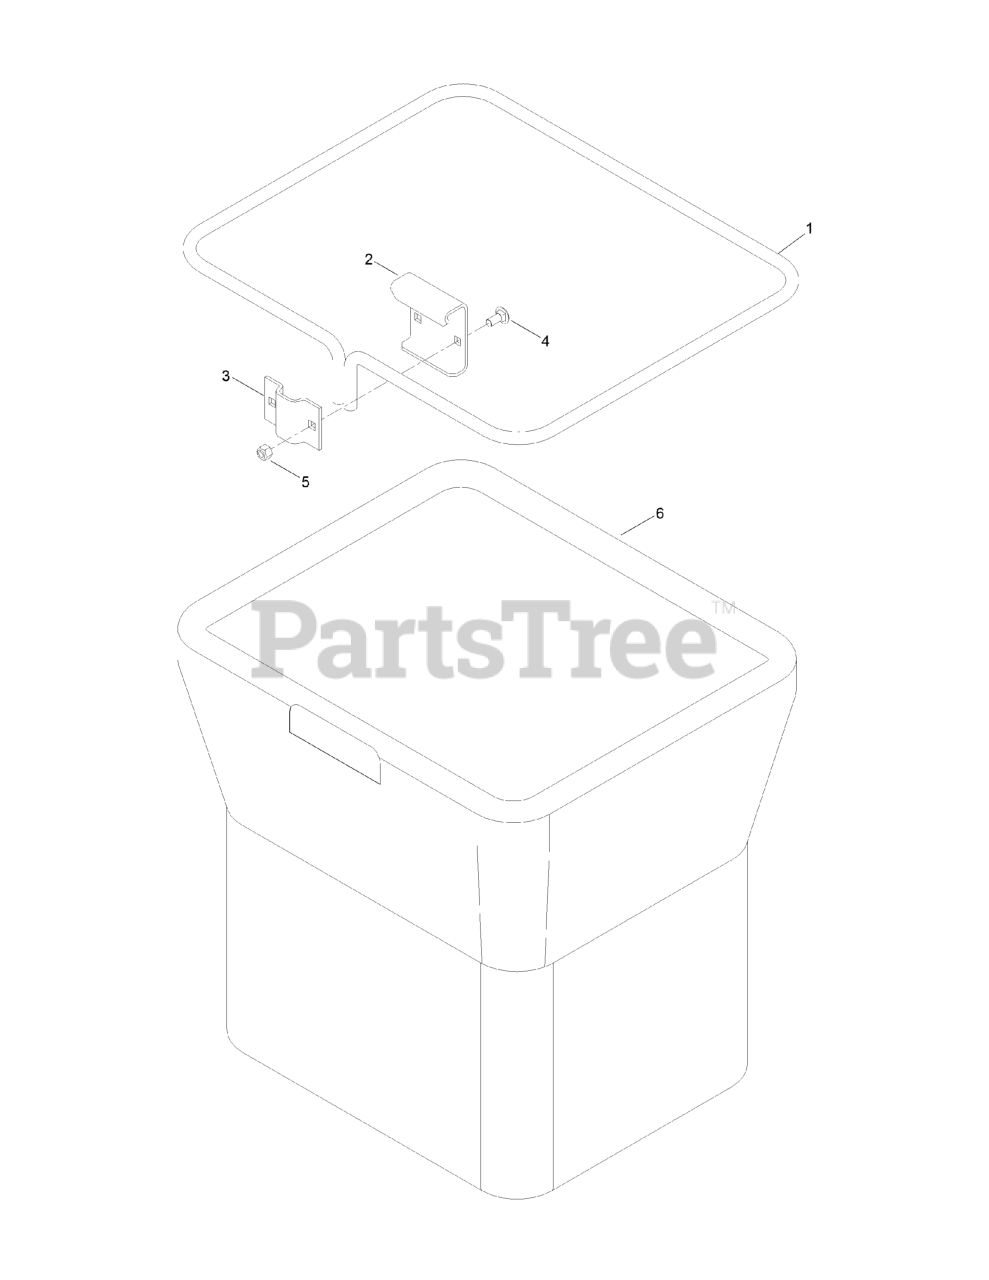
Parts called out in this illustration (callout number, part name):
1	FRAME-BAG
2	HANGER-BAG
4	BOLT-CARR
5	NUT-HEX
6	BAG
